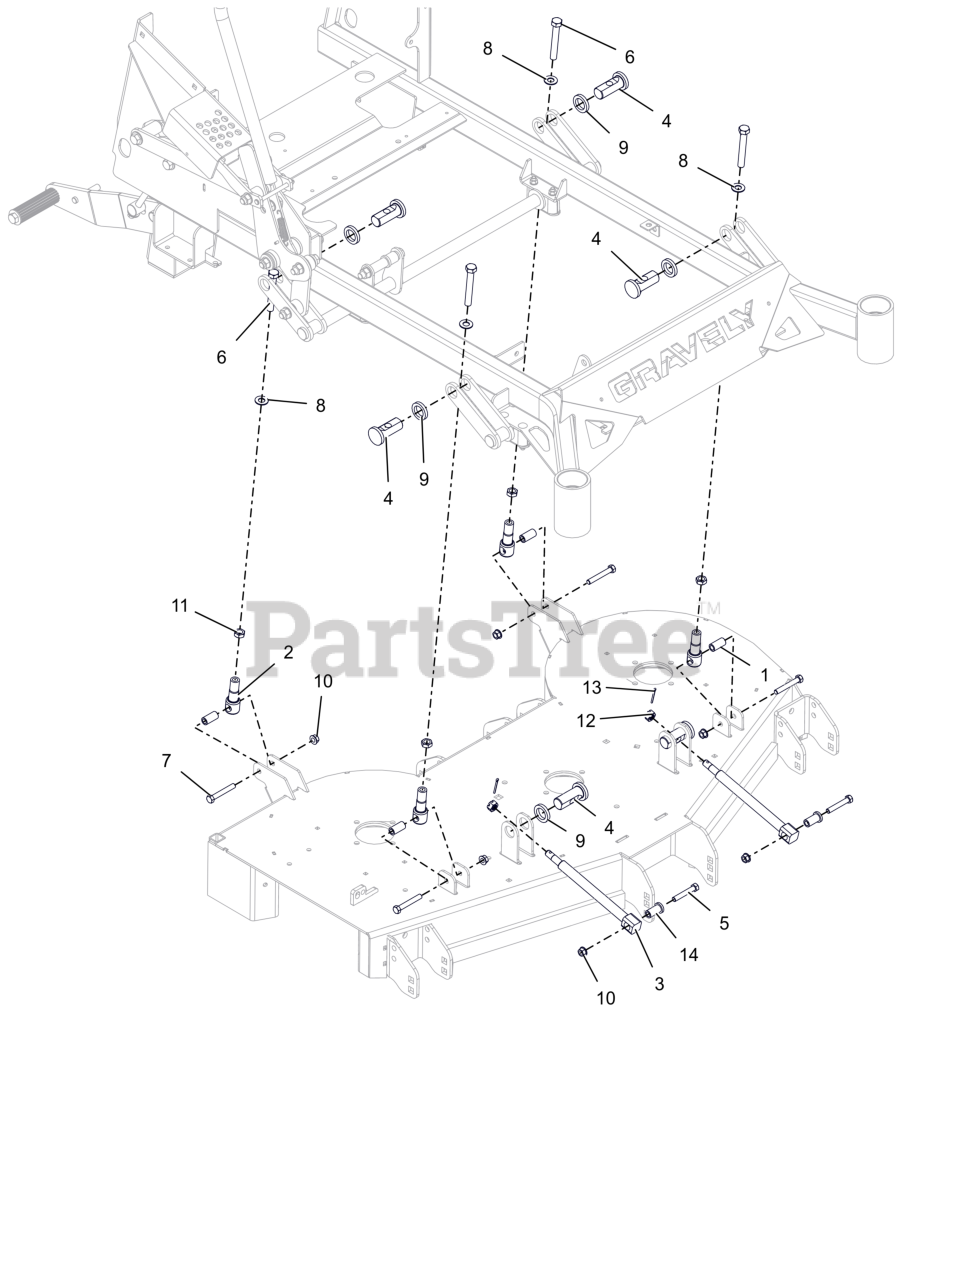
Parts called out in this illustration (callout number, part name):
1	SPACER, DECK LEVELING
2	LINK, DECK LIFT FORMED
3	DRAG,LINK-HD
4	PIN, DECK LIFT
5	BLT,HEX .38-16X2.25 G5 ZCC
6	BLT, HEX 0.5-13X3.5F GR5 ZCC
7	BLT, HEX .38-16X2.50 G8 ZCC
8	WSHR, FLT .557X1.040X.102 ZCC
9	WSHR-FL-STL 1.0X1.50X.25
10	NUT-LK-CTR-FLG .375-16 GF ZCC
11	NUT-JAM .500-13 G2 ZCC
12	NUT-SL .50-13
13	PIN,CTR.12X1.25EXTPRSQCT ZC120
14	SPCR, DRAG LINK
